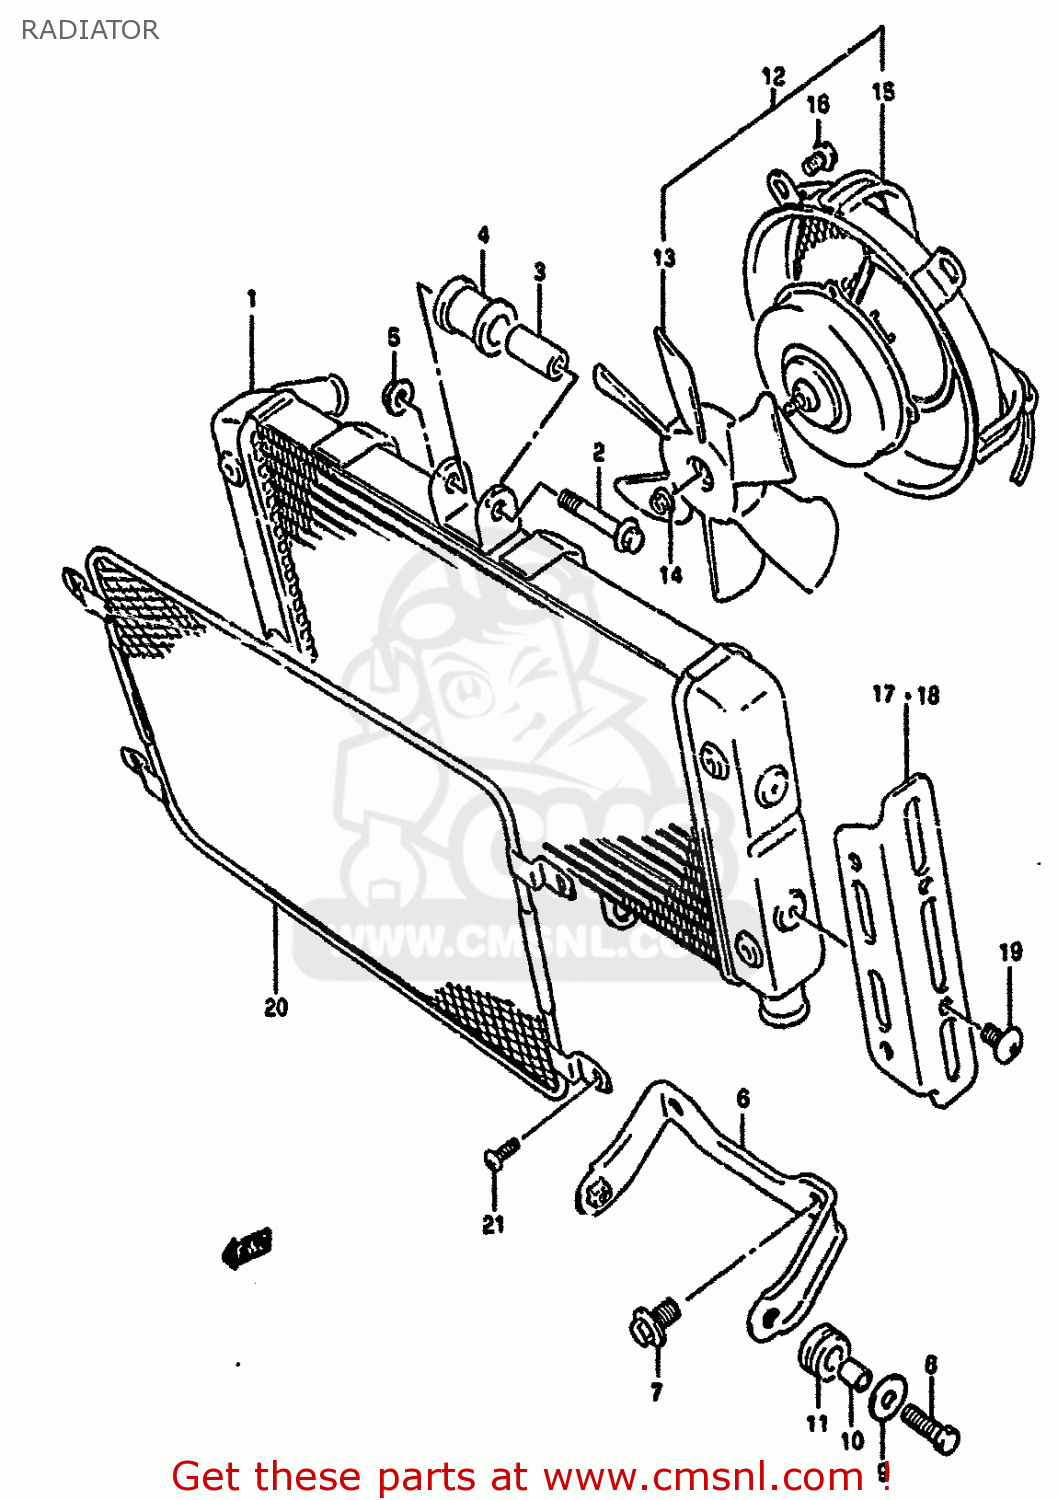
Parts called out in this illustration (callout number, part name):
1	RADIATOR ASSEMBLY,WATER
2	BOLT (6X45)
3	SPACER
4	CUSHION
5	NUT 6MM
6	BRACKET COMP,ROTOR,LOWER
7	BOLT, LOWER
8	BOLT 6X20
9	WASHER (6.5X22X1.6)
10	SPACER (6.8X10X12)
11	CUSHION
12	FAN ASSY,RADIATOR
13	FAN ASSY
14	NUT
15	SHROUD,FAN
16	BOLT
17	COVER,RADIATOR,R
18	COVER,RADIATOR
19	SCREW(6X12)
20	NET,RADIATOR
21	SCREW(4X12)
